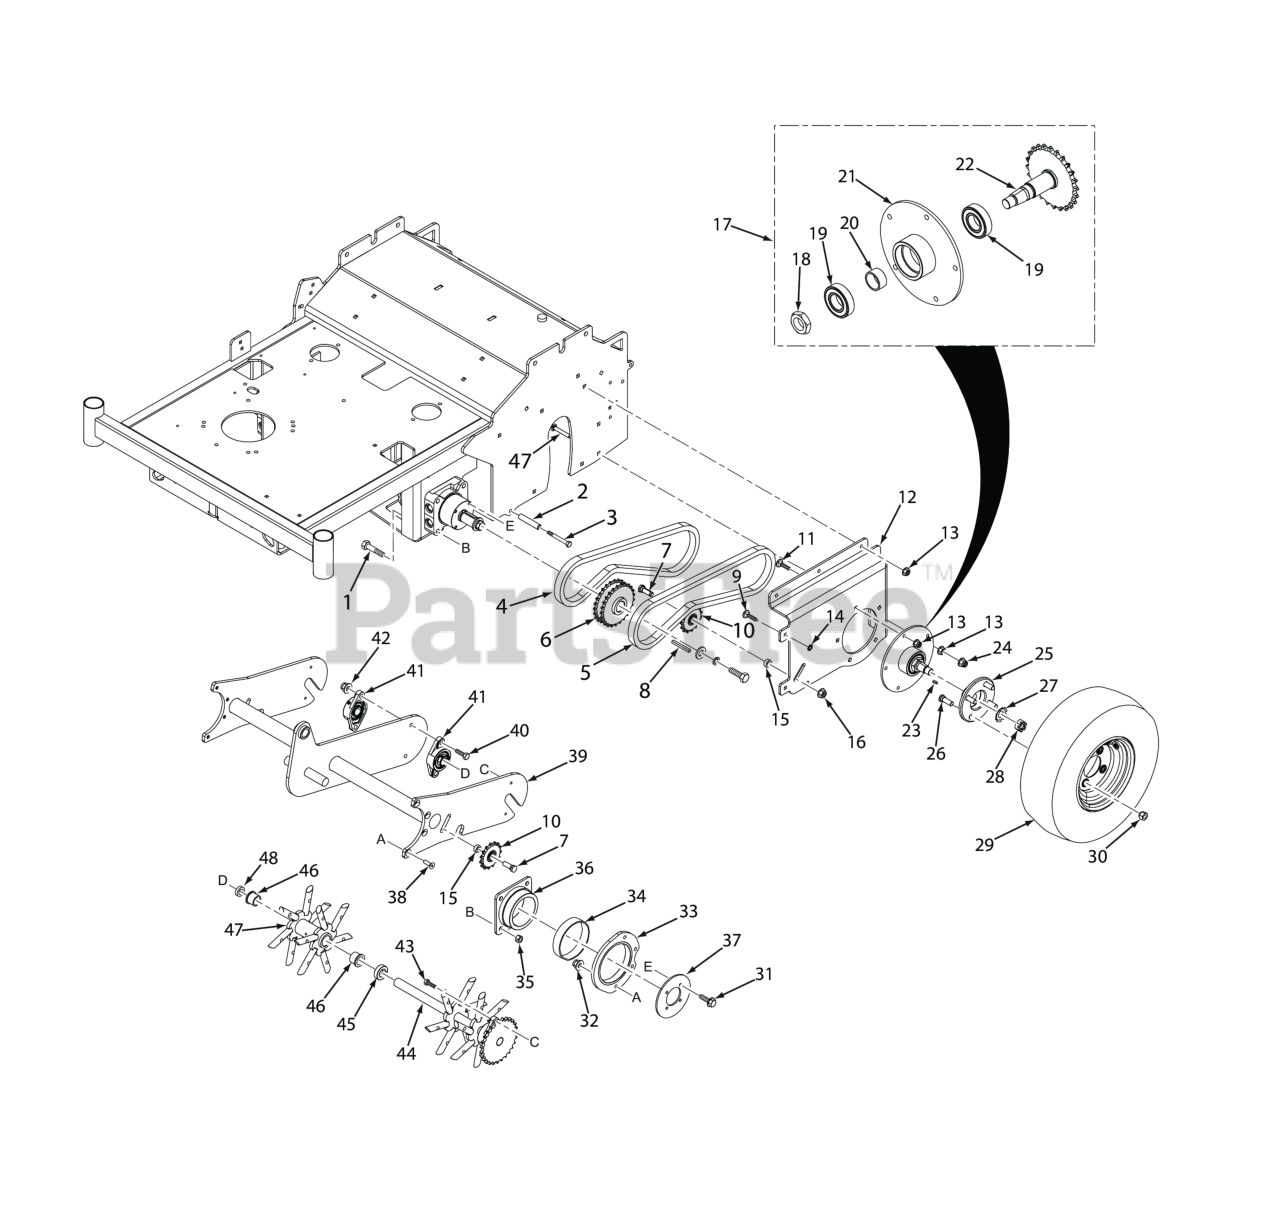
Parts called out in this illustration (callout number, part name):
1	Bolt, Hex Head 1/2-13 x 2-3/4" (48V & 52V - One Weight)
2	Spacer, Wheel Mount
3	Bolt, Hex Head 3/8-16 x 4.00
4	Chain, Tine Drive
5	Chain, Wheel Drive
6	Sprocket, Motor
7	Bolt, Ilder Sprocket
8	No Part Description Available
9	Bolt, 5/16-18 x .75 RHSN Carriage
10	Sprocket, Idler 15T
11	Carriage Bolt, 3/8-16 x 1.0"
12	Bracket LH, Wheel Mount
13	NUT, 3/8-16 SERRATED FLANGE HEX HEAD
14	Nut, Push-On 5/16-18
15	Bushing, Idler Sprocket
16	Nut, Hex Serrated Flange 1/2-13
17	Assembly (incl. #18, 19, 20, 21, 22)
18	Nut , Spec ial 1 -1/ 1 6 - 1 8
19	Bearing, Ball 30mm Bore x 62mm OD
20	Spacer, Wheel Bearing
21	Hub, Wheel
22	Shaft, Wheel
23	KEY, WOODRUFF #9, 3/16 X 3/4"
24	NUT, 3/8-16 SERRATED FLANGE HEX HEAD
25	Wheel Hub Assembly
26	Bolt, Serr. Flange 1/2-20 x 4.563"
27	Lock Washer, Wheel Motor
28	Hex Castle Nut, 3/4-28 UNEF
29	Wheel Assy., 18 x 6.5 - 8
30	Wheel Nut, 1/2-20 x 13/16
31	Capscrew, 5/16-18 x .75 Serrated Flange Hex Head
32	HEX NUT, ELASTIC STOP LOCK, 3/8-16
33	Pivot Bearing Wlmt
34	Pivot Bearing
35	Locknut, Hex 1/2-13 Center Lock
36	Pivot Bearing Wlmt
37	Stop Plate, Pivot Bearing
38	Capscrew, 3/8-16 x 1-1/4"
39	Pivot Arm Wlmt
40	BOLT, HEX HEAD, 7/16-14 X 1-3/4
41	Bearing, 1" Flange
42	HEX NUT, 7/16-14 SERRATED FLANGE
43	Bolt, Hex Head 7/16-20 x 1"
44	Tine Wlmt, LH Drive
45	Clamp Collar, 1.25 Bore 2 Piece
46	Bushing, 1" ID Oilite
47	Tine Wlmt, Idler
48	Flatwasher, 1" (1.062 x 1.75 x .10)
